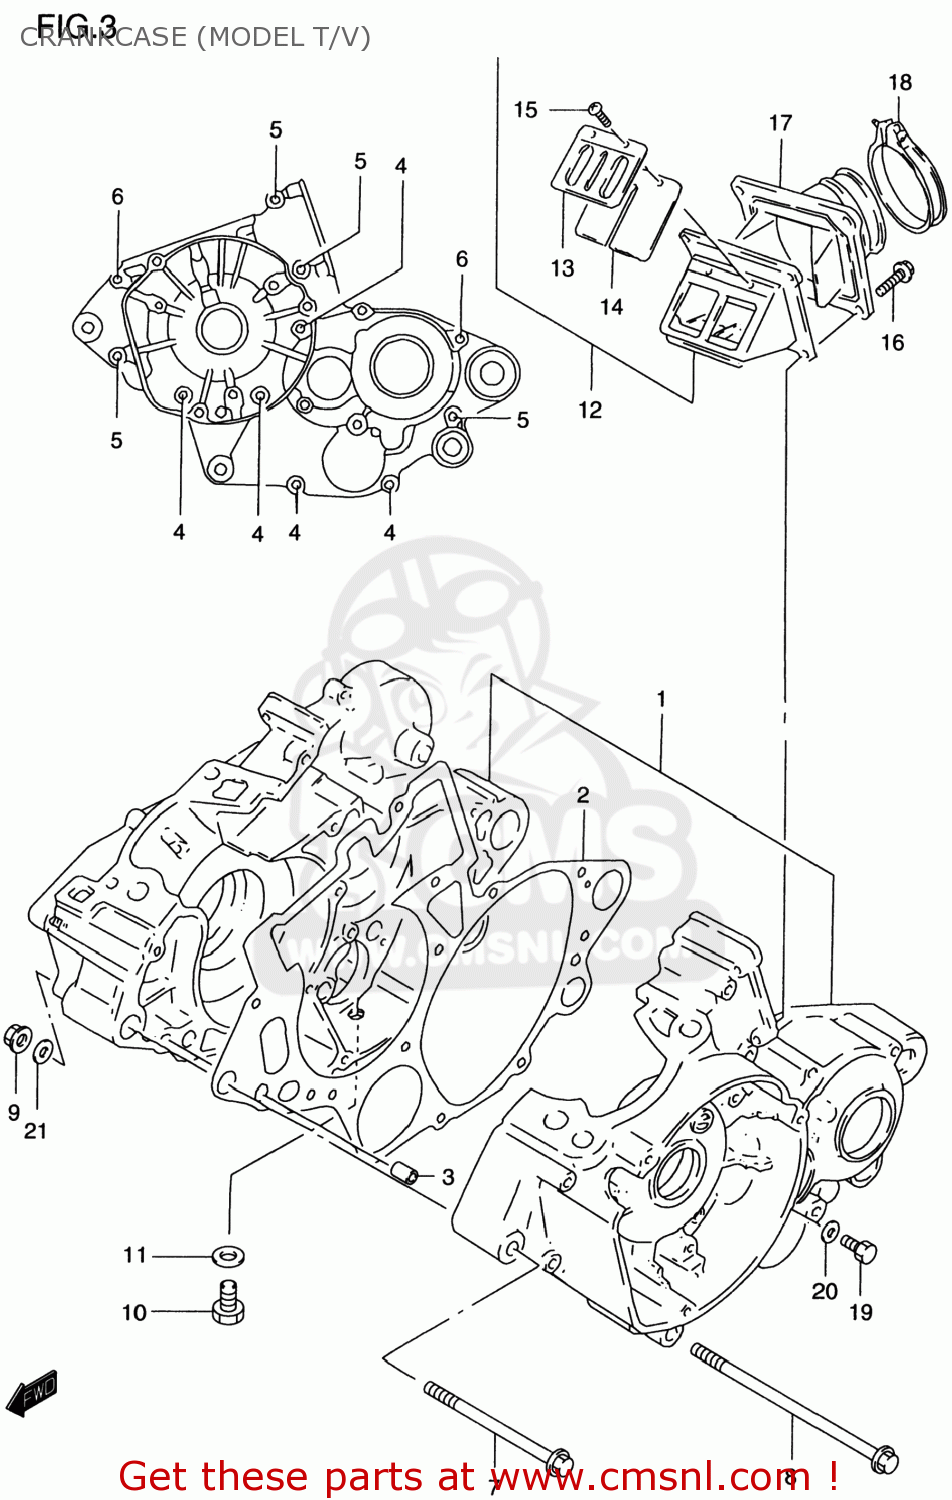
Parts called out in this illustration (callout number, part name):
1	CRANKCASE SET
2	GASKET,CRANKCASE (NAS)
3	PIN
4	BOLT
5	BOLT
6	BOLT
7	BOLT(8X88)
8	BOLT(8X125)
9	NUT
10	Bolt
11	GASKET(12.1X16.2X3.7) (NAS)
12	VALVE ASSEMBLY,REED
13	STOPPER,REED VALVE
14	VALVE,REED
15	SCREW
16	SCREW
17	PIPE COMP,INTAKE
18	CLAMP
19	SCREW(6X10)
20	GASKET(6.2X11X1).2 (NAS)
21	WASHER
